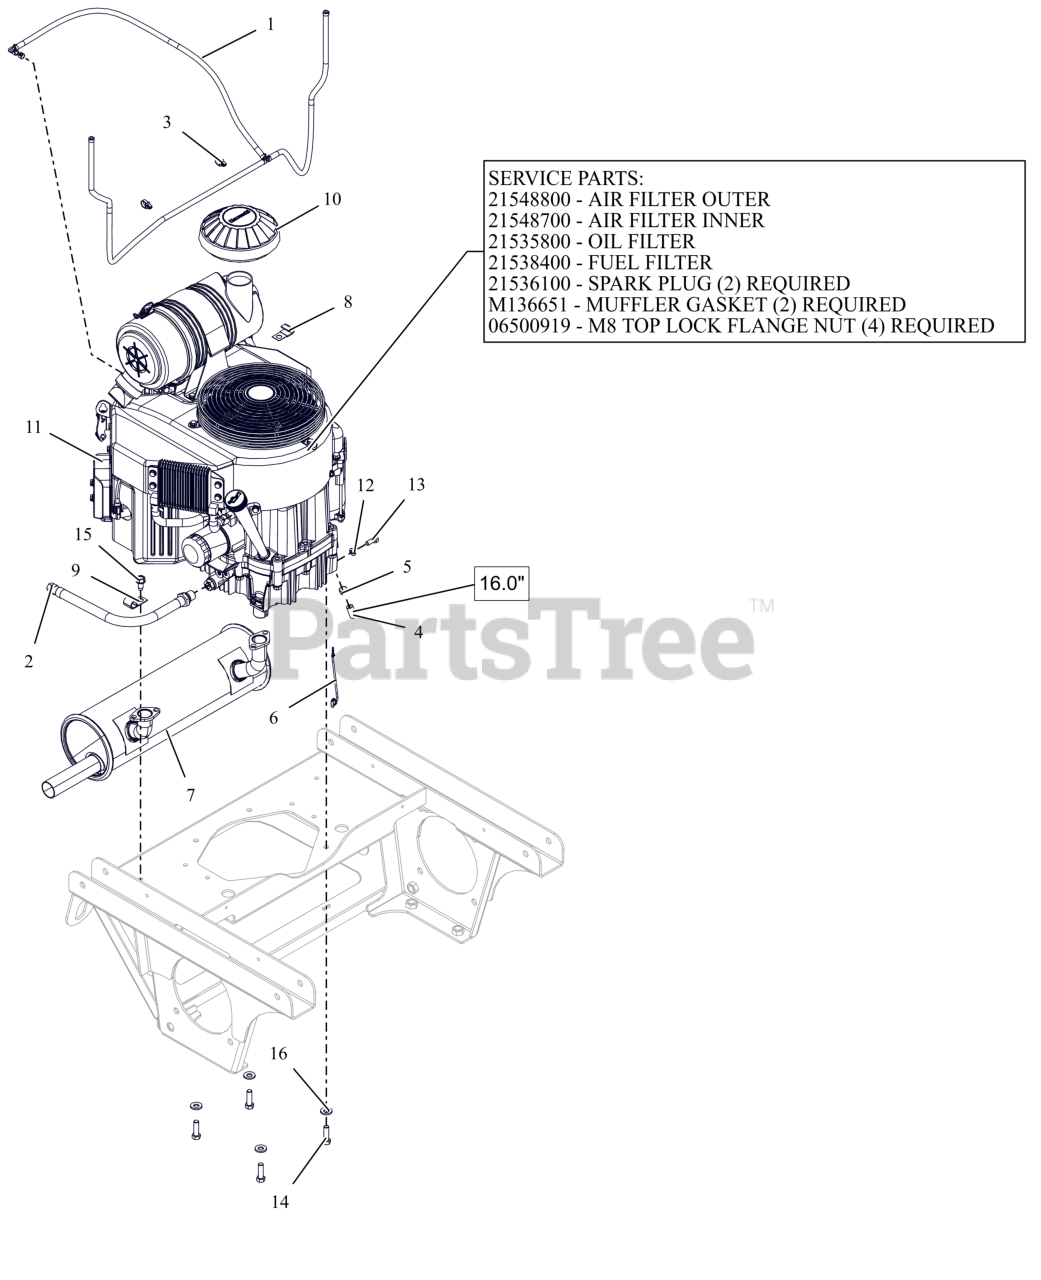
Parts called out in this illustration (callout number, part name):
1	ASM, VAPOR LINE
2	HOSE, OIL DRAIN
3	ROUTING CLIP (1/2" ID)
4	HOSE, .25 LOW-PERM BULK GAS
5	CLAMP, FUEL LINE
6	LEAD - STARTER SOLENOID
7	MUFFLER, 27-31 KAW
10	CAP, AIR CLEANER INTAKE (2")
11	ENGINE, KAWASAKI FX850
11	FILTER, OUTER
11	FILTER, INNER - KAW
11	FILTER,OIL - KAW
11	FUEL FILTER - KAWASAKI
11	PLUG, SPARK
11	GASKET, MUFFLER #
11	NUT-LK-TOP-FLG M8 ZCC
12	WSHR,LK-REG .312X.078 ZCC
13	BLT, HEX M8-1.25X20 G8.8 ZCC
14	BLT, HEX .38-16X1.25 G5 ZCC NT
15	SCR,TAP .375-16X.75 HWH TR ZCC
16	WASHER, 3/8" SPRING DISC
